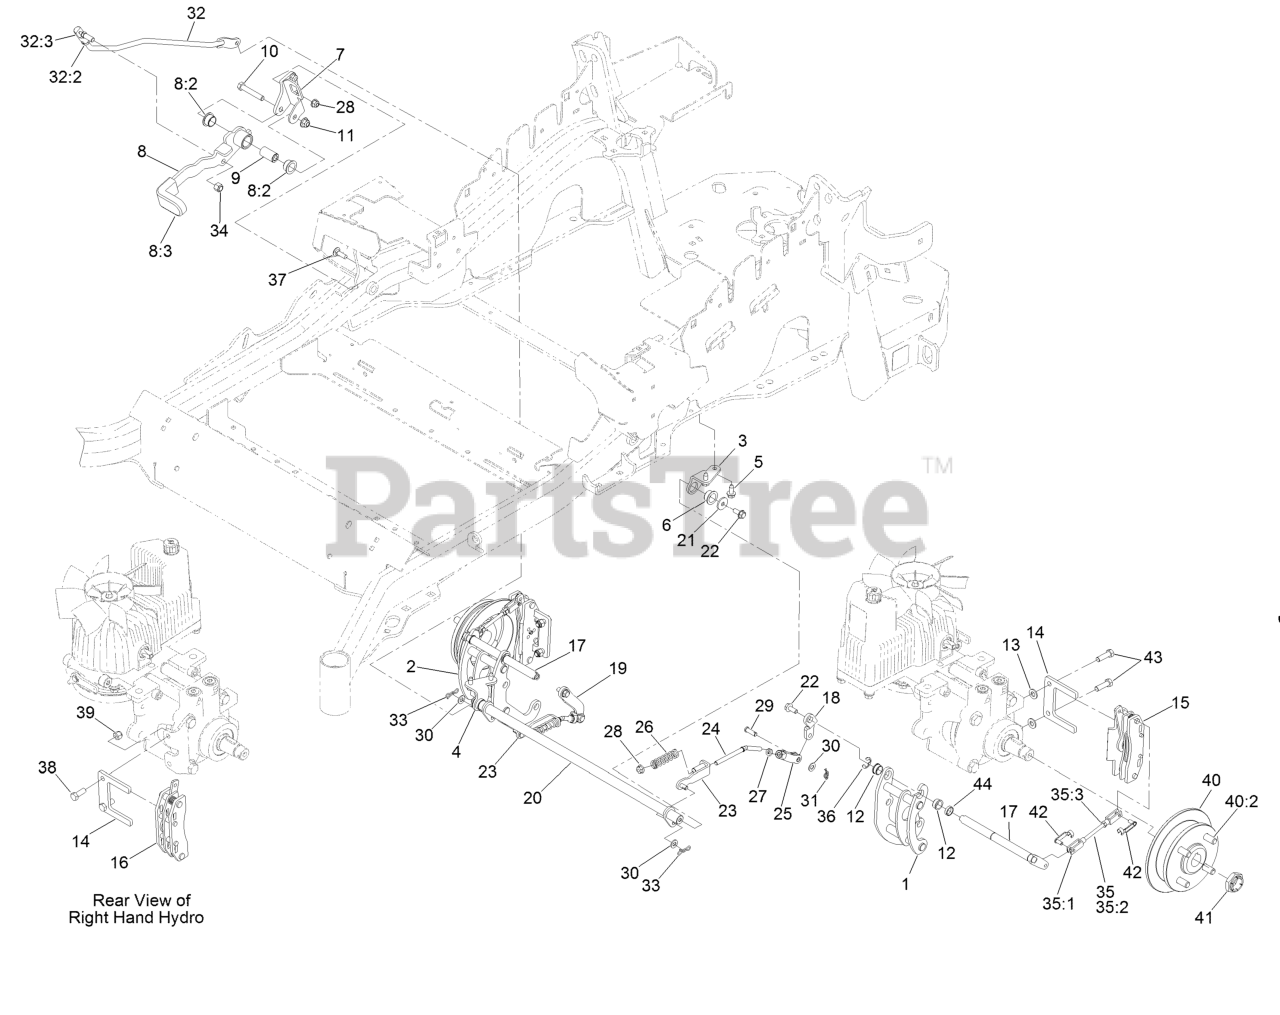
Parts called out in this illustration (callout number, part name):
1	Mount-Bellcrank, LH
2	Mount-Bellcrank, RH
3	Mount-Pivot, LH
4	Mount-Pivot, RH
5	Screw-HWHTF
6	Bushing-Flange
7	Bracket-Mount
8	Brake Lever ASM W/ Grip
8:2	Bushing-Flange
8:3	Grip-Lever
9	Handle-Pivot, Brake
10	Screw-HH
11	Nut-HF, NI
12	Bushing
13	Washer-Flat
14	Plate-Mount, Brake
15	Caliper-Brake
16	Caliper-Brake, RH
17	Bellcrank
18	Arm-Inner, LH
19	Arm-Inner, RH
20	Shaft-Cross
21	Washer-Flat
23	Bracket-L
24	Linkage-Mid
25	Yoke-Offset
26	Spring-Compression
27	Nut-Jam
28	Nut-HF, NI
29	Pin-Clevis
30	Washer-Plain
31	Pin-Cotter, Locking
32	Front Linkage ASM
32:2	End-Tie Rod, RH
32:3	Nut-HJ
33	Pin-Cotter, Locking
34	Nut-Lock
35	Rear Linkage ASM
35:1	Yoke
35:2	Linkage, Rear
35:3	Nut-Jam
37	Bolt-CARR
38	Screw-HH
39	Nut-Lock, NI
40	Wheel Hub ASM
40:2	Stud-Wheel
41	Locknut
42	Pin-Clevis, Spring
43	Screw-Lock, Patch
